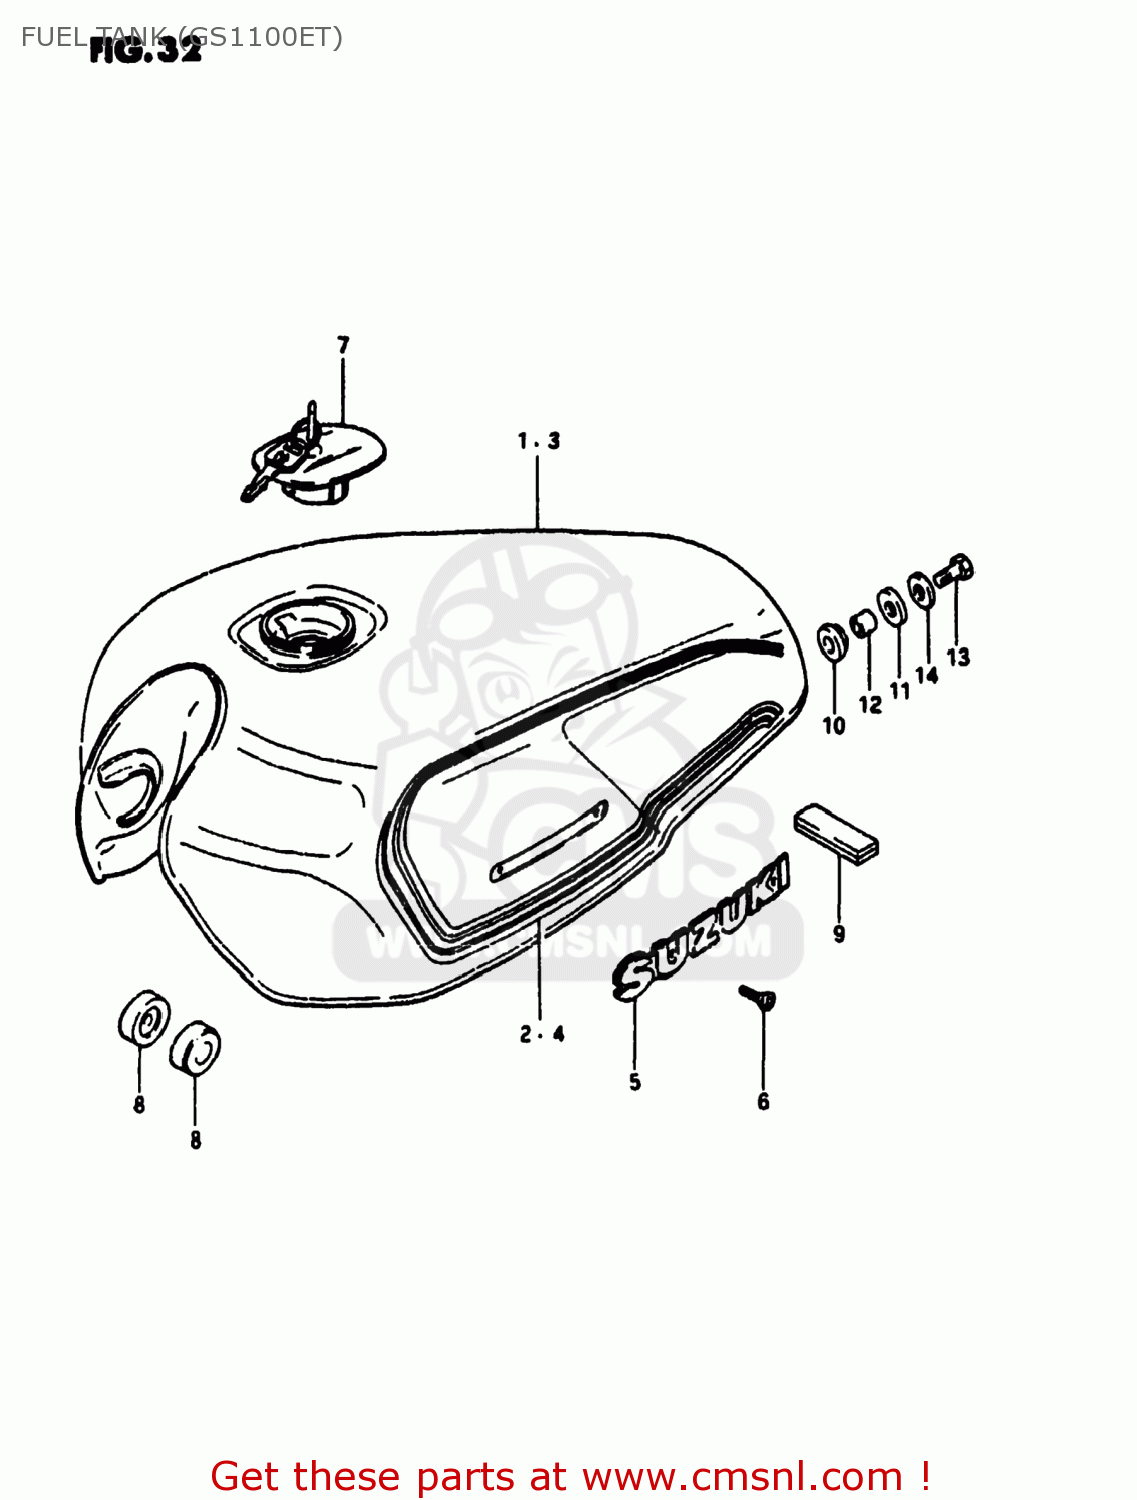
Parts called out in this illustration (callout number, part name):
1	TANK ASSEMBLY,FUEL
3	TANK ASSEMBLY,FUEL
5	EMBLEM,FUEL TANK
6	SCREW 3X6
7	CAP SET,FUEL TANK
8	CUSHION
9	CUSHION
10	CUSHION
11	CUSHION
12	SPACER(8.5X12X19)
13	BOLT (8X30)
14	WASHER (8.5X29X1.6)
